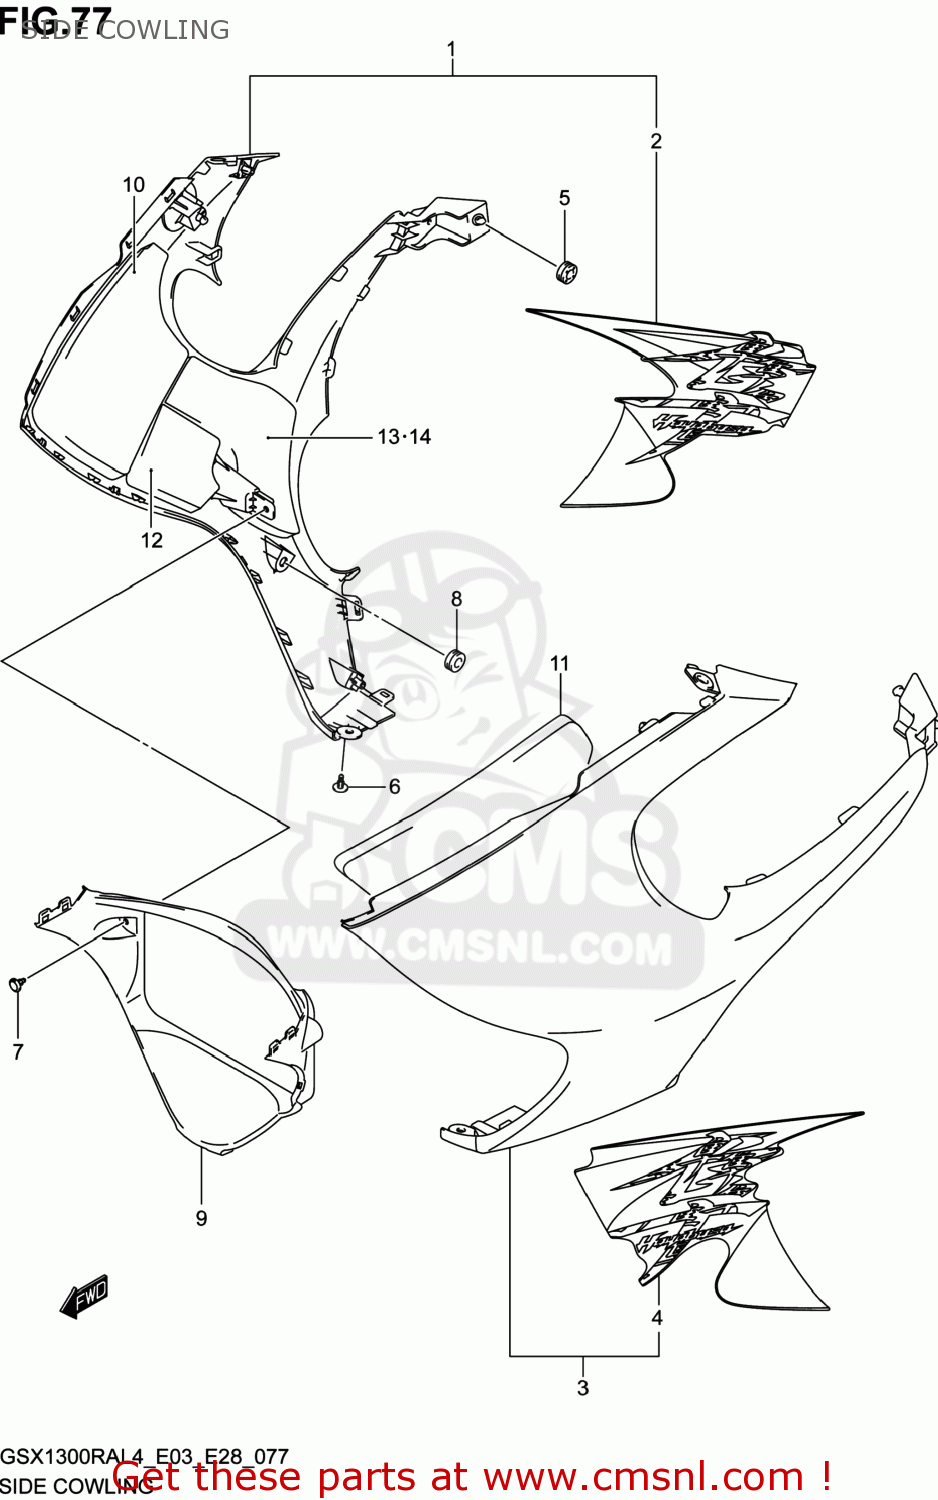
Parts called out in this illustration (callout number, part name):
1	COWLING,SIDE,R(WHITE)
2	TAPE,SIDE COWLING,R
3	COWLING,SIDE,L(WHITE)
4	TAPE,SIDE COWLING,L
5	CUSHION
6	CLIP
7	CLIP
8	CUSHION
9	COWLING,UNDER CTR
10	CUSHION,SIDE COWL,R
11	CUSHION,SIDE COWL,L
12	CUSHION,SIDE COWL
13	SHIELD,SIDE COWL,R
14	SHIELD,SIDE COWL,L
